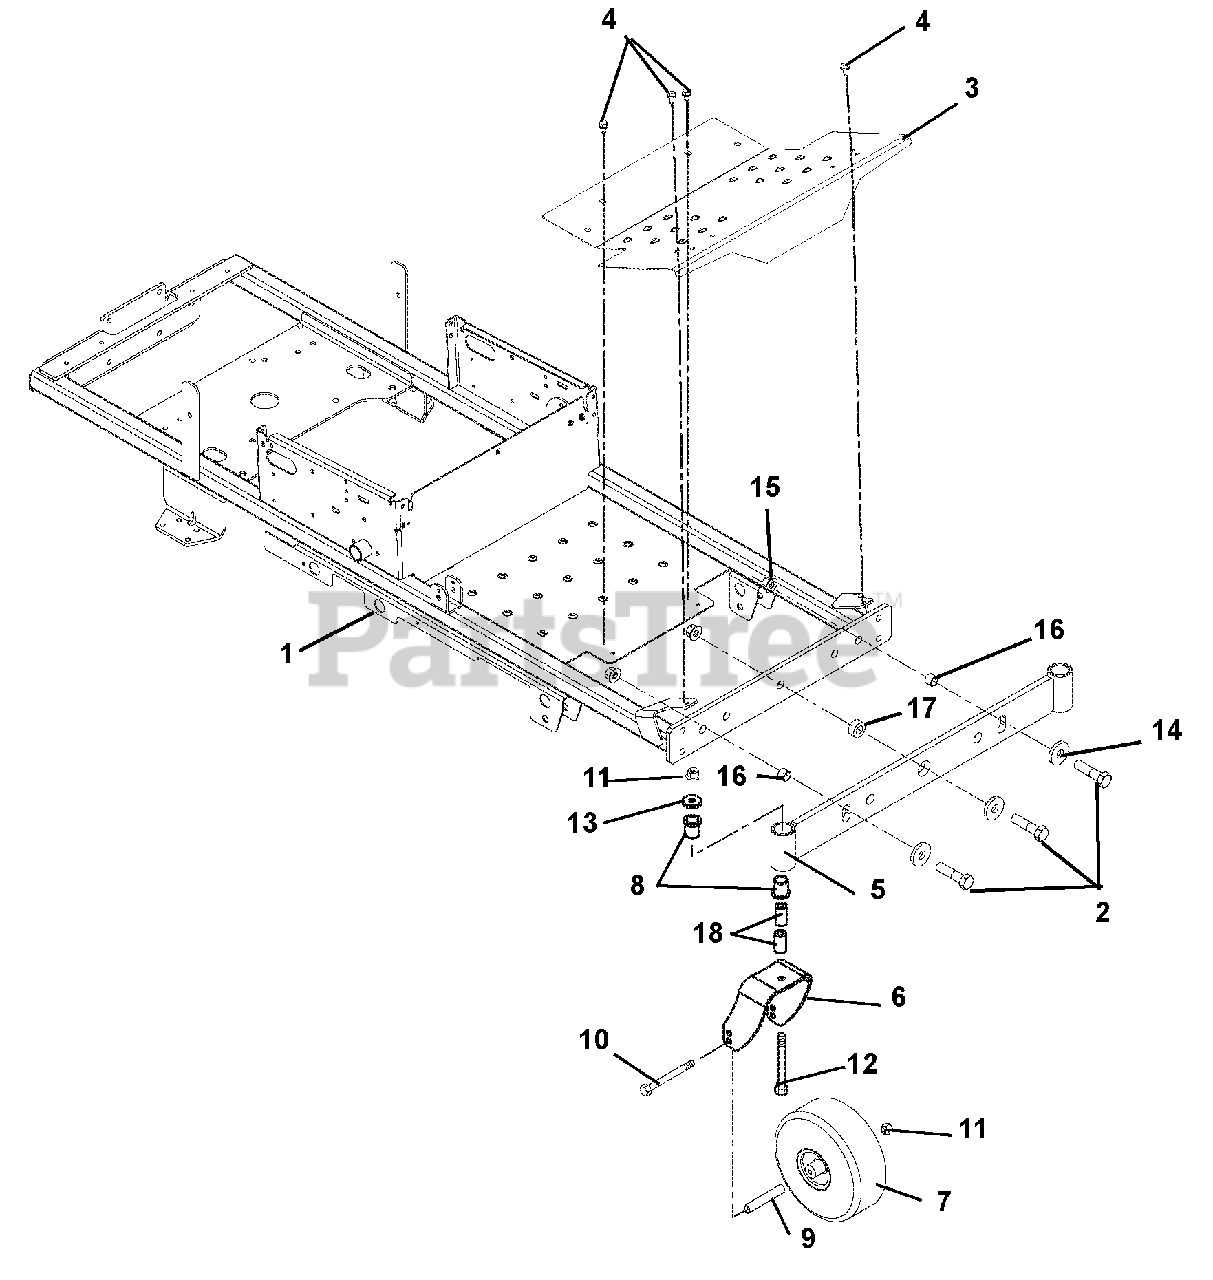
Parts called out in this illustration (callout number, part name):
1	WMT, ZOOM FRAME
2	BLT-HEX .62-11X2.25 YWZC GR8
3	FOOTREST, MZ/ZOOM
4	@SCR-TAP .31-18X.50 HWH TR YWZ
5	WELDMENT, FRONT AXLE
6	FORK, CASTER- WELDED
7	TIRE/WHEEL ASSY, 11X4-5
8	BSHG-FLG 1.00X1.25X1.50X1.50EP
9	SPACER, ROLLED WHEEL
10	@BLT-HEX .50-13X6.50 GR5 YWZC
11	@NUT-LK-NYL-FLG .50-13 YWZC
12	@BLT-HEX .50-13X5.00 GR5 YWZC
13	WSHR-FL-STL.511X1.441X.125 YWZ
14	WSHR-FLT .640X1.75X.250 YWZC
15	@NUT-LK-NYL-FLG .63-11 YWZC
16	SPACER, .750 D X .558 LONG
17	BUSHING, AXLE PIVOT
18	SPACER, CASTER .50X1.00X1.84
